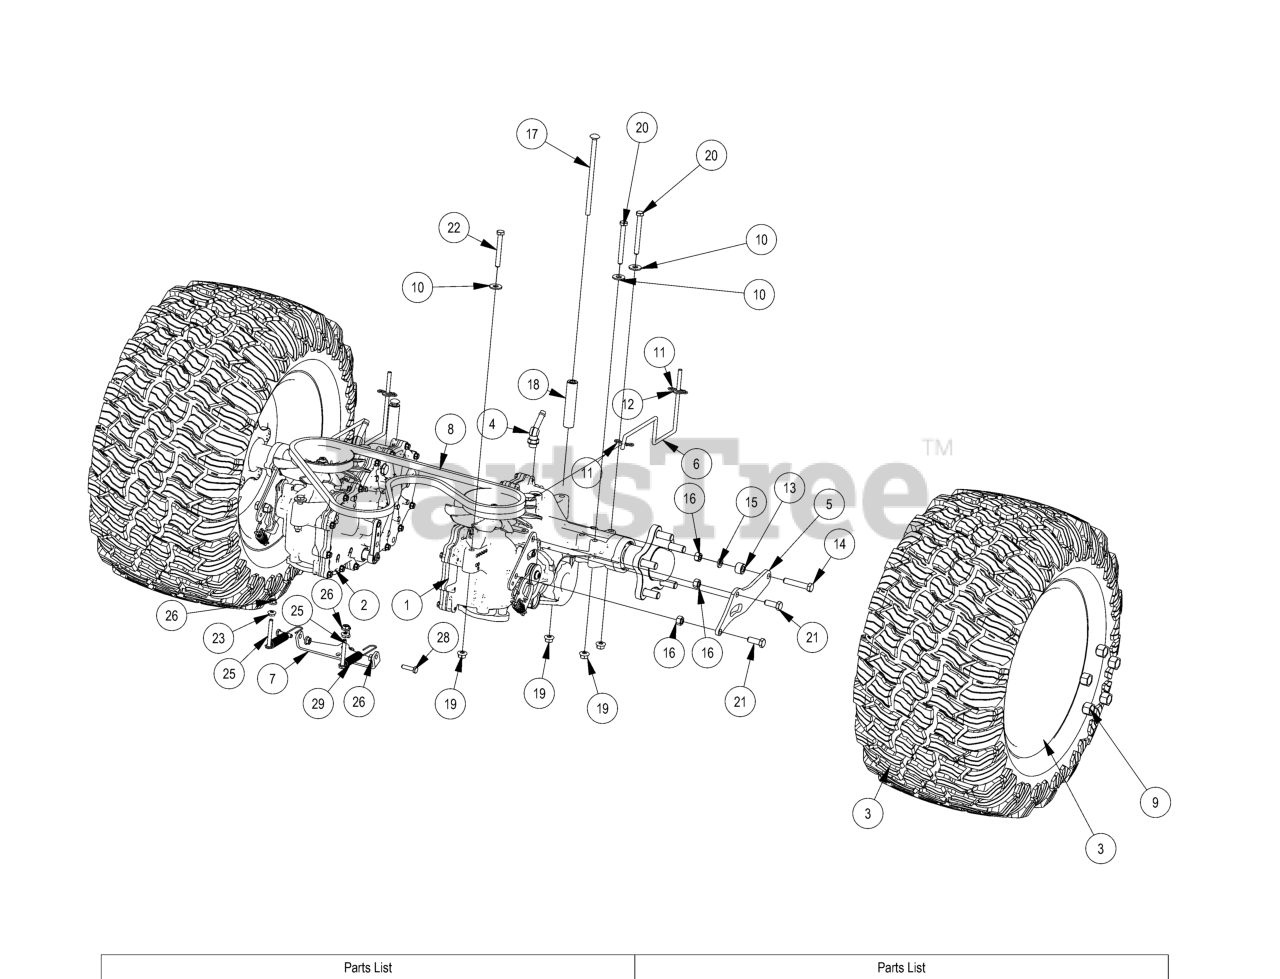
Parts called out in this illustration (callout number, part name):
1	Compact Outlaw/Revolt Transaxle Left 3400
2	Compact Outlaw/Revolt Transaxle Right 3400
3	23x11-12 Reaper Turf Assembly
4	ZT Fitting, 3/8 x 3/8 45 Degree, 4603-6-6
5	Control Arm Plate 2019 Stand On
6	2019 Stand On Neutral Rod
7	Brake Bracket
8	2019 Stand On Pump Belt (Timken# 47-2827)
9	Acorn Lug Nut
10	5/16 USS FLAT WASHER (7/8 OD) ZINC
12	1/4 USS FLAT WASHER (3/4 OD) ZINC
13	ACS Spacer 3/4x3/8x1/2
14	3/8-16 X 2 HEX CAP SCREW (GR.5) ZINC
15	3/8 SPLIT LOCKWASHER ZINC
16	3/8-16 HEX NUT ZINC
17	5/16-18 X 6 CARRIAGE BOLT (GR.5) ZINC
18	2017 Transaxle Spacer
19	5/16-18 NYLON INSERT FLANGE LOCKNUT ZINC
20	5/16-18 X 3 HEX CAP SCREW (GR.5) ZINC
21	3/8-16 X 1 GR 5 Hex Bolts Zinc
22	5/16-18 X 2-1/2 HEX CAP SCREW (GR.5) ZINC
23	1/4-20 HEX SERRATED FLANGE NUT HARD/ZINC
24	1/4-20 NYLON INSERT LOCKNUT ZINC
25	1/4-20 X 2 HEX CAP SCREW (GR.5) ZINC
26	1/4-20 NYL INSERT FLANGE LOCKNUT ZINC
27	1/4-20 X 3/4 HEX CAP SCREW (GR.5) ZINC
28	1/4-20 X 1 HEX CAP SCREW (GR.5) ZINC
29	Brake Spring
